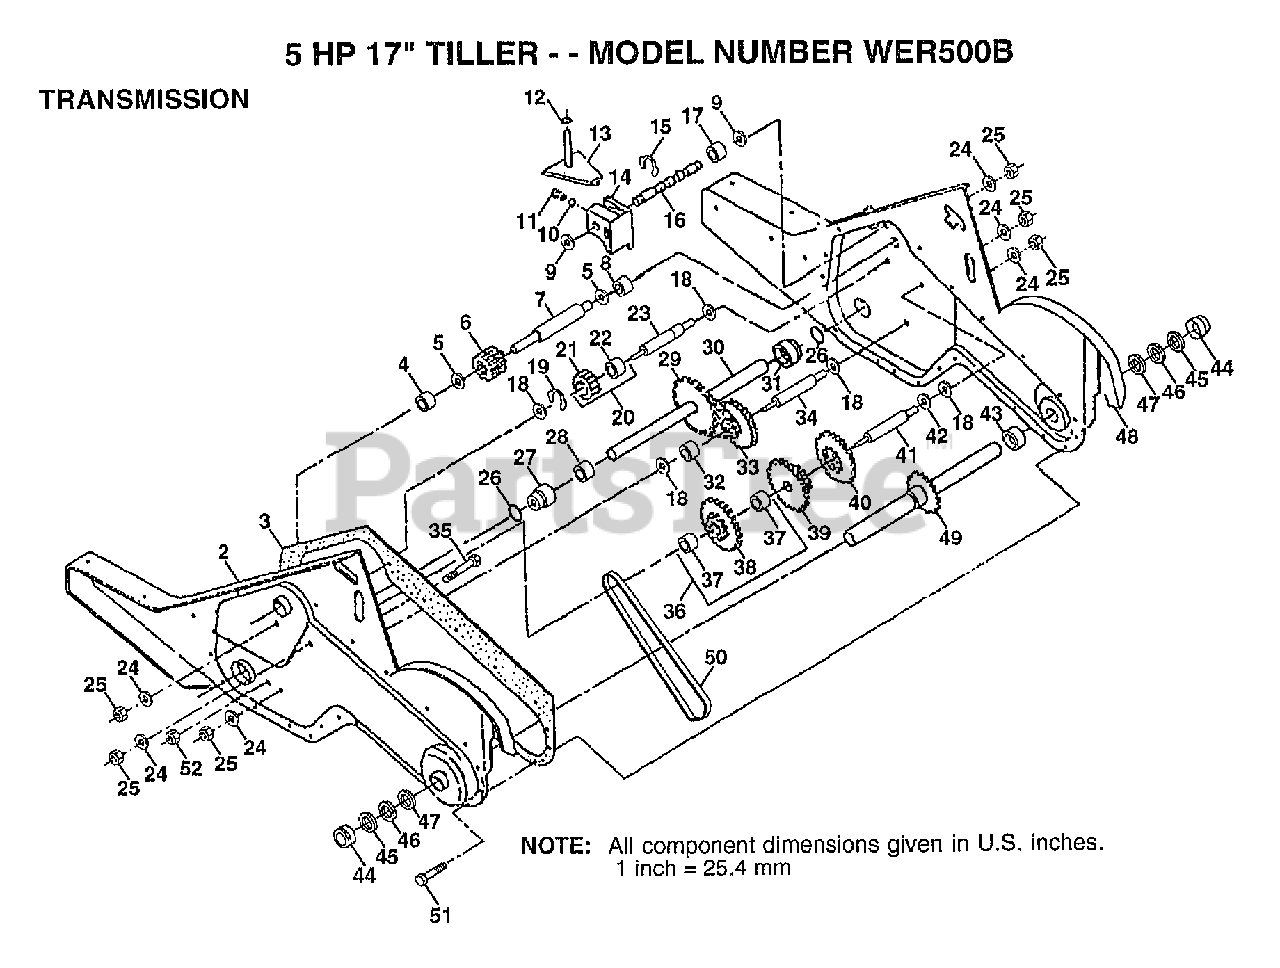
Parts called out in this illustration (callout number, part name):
3	GASKET TI
4	NEEDLE BRNG LT
5	"T, BEARING"
6	PINION-INPUT CRT
7	SHAFT-INPUT CRT
8	"TI, BEARING"
9	WASHER SEAL CRT
11	SPRING-SHIFT CRT
12	O-RING TI
13	ARM ASSY CRT
14	SHIFT FORK TI
15	KLIP RING
16	SHAFT SHIFT CRT
17	SPACER SPLIT CRT
18	WASHER
19	KLIP RING
20	GEAR ASSY CRT
21	GEAR-REV IDLR CRT
22	NEEDLE BEARING TI
23	SHAFT CRT
24	LOCKWASHER
25	NUT.ASF.HEX.7/16
26	O RING CRT
27	"CRT, BEARING"
28	BUSHING TI
29	CHAIN CRT
32	SPACER TI
33	SPRCKT 8 GEAR CRT
34	SHFT 2ND RED. CRT
35	SCRW WHIZ LOK CRT
36	SPROCKET ASM.
37	BEARING
39	GEAR TI
40	GEAR TI
41	REDUCTION SHFT TI
42	BRNG RACE
43	SPACER TI
44	CUP.FORMED.
45	RING SPIRAL CRT
49	TINE SHAFT
50	CHAIN.50 LINK TI
51	SCREW CRT
52	NUT.HEX.5/16-18
